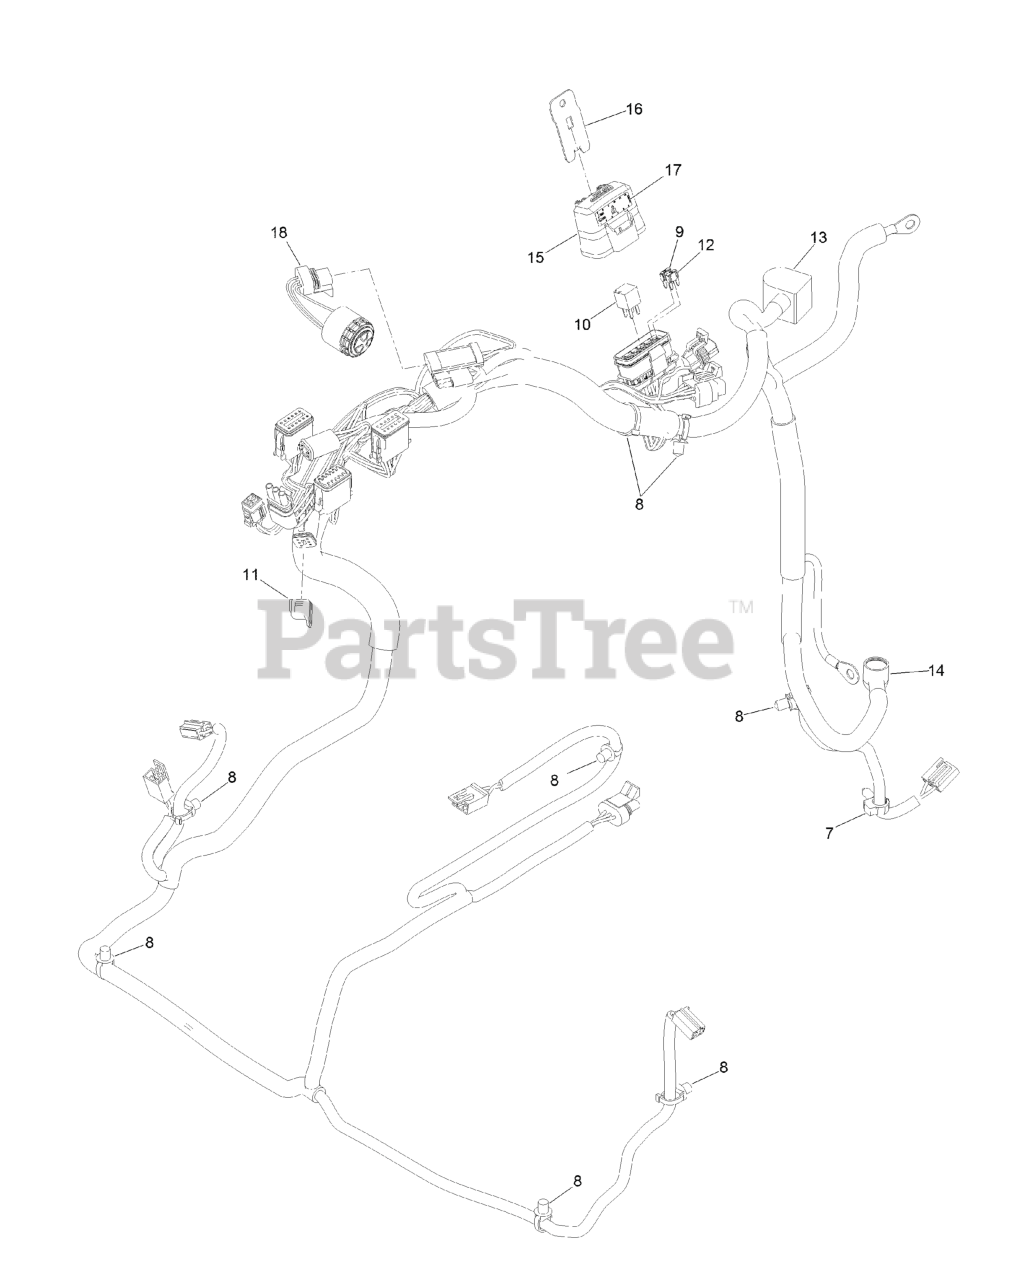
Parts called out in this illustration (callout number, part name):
7	CLIP-HARNESS
8	CLIP-TIE
9	FUSE-MINI BLADE, 20 AMP
10	RELAY-MICRO
11	CAP-PLUG, 6 WAY
12	FUSE-MINI BLADE, 15 AMP
13	INSULATOR-BATTERY
14	INSULATOR-SOLENOID
15	COVER-BLOCK, FUSE
16	CLIP-MOUNTING
17	DECAL-FUSE
18	ALARM-DUAL TONE
